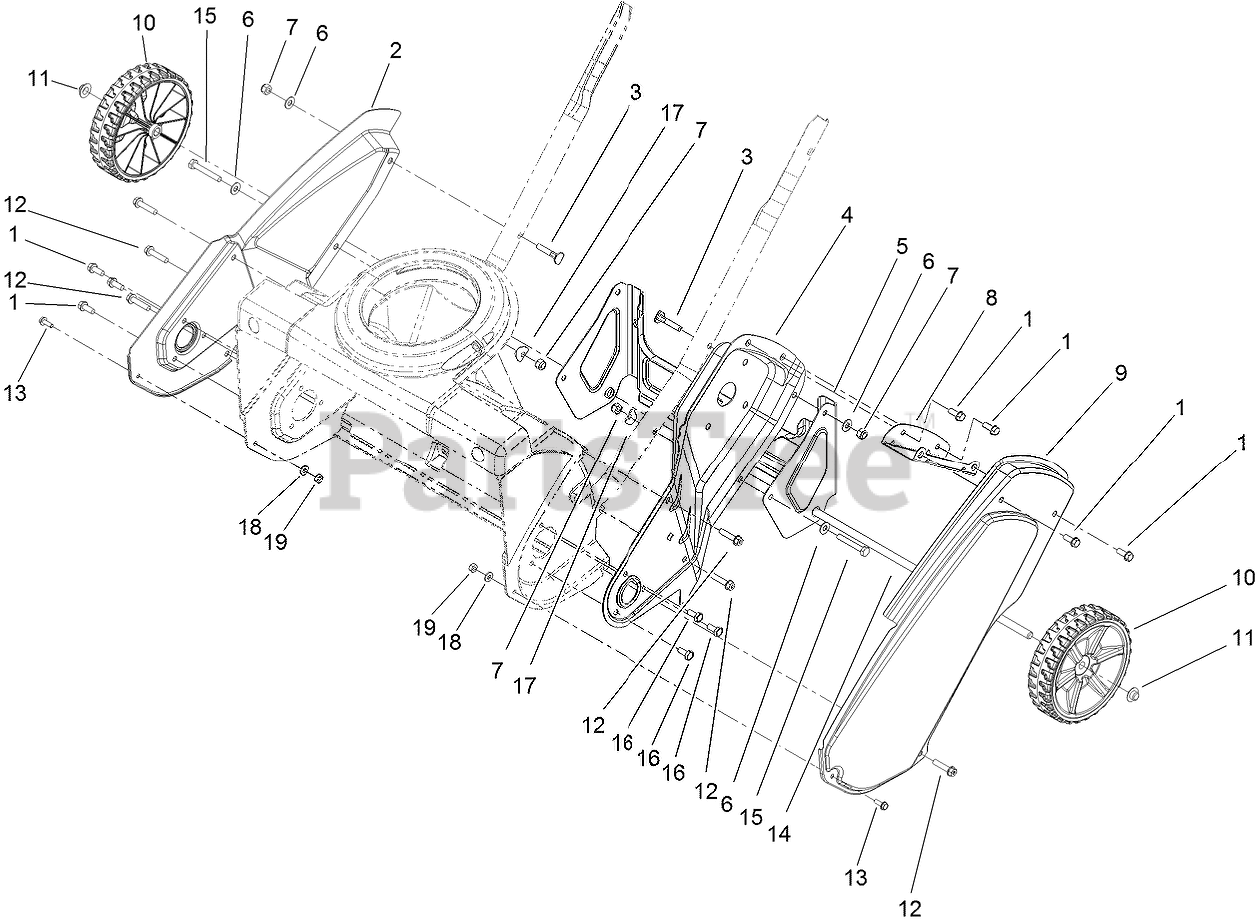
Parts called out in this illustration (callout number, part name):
1	SCREW-HWH
2	SIDEPLATE-RH
3	SCREW-HANDLE
4	SIDEPLATE-LH
5	BRACKET-WHEEL
6	WASHER-FLAT
7	NUT-LOCK, NI
8	BRACKET-COVER, BELT
9	COVER-BELT
10	WHEEL ASM
11	NUT-PUSH
12	SCREW-PLASTIC
15	SCREW-HH
16	SCREW-HH, TAPTITE
17	WASHER
18	WASHER-FLAT
19	NUT-LOCK, NI
